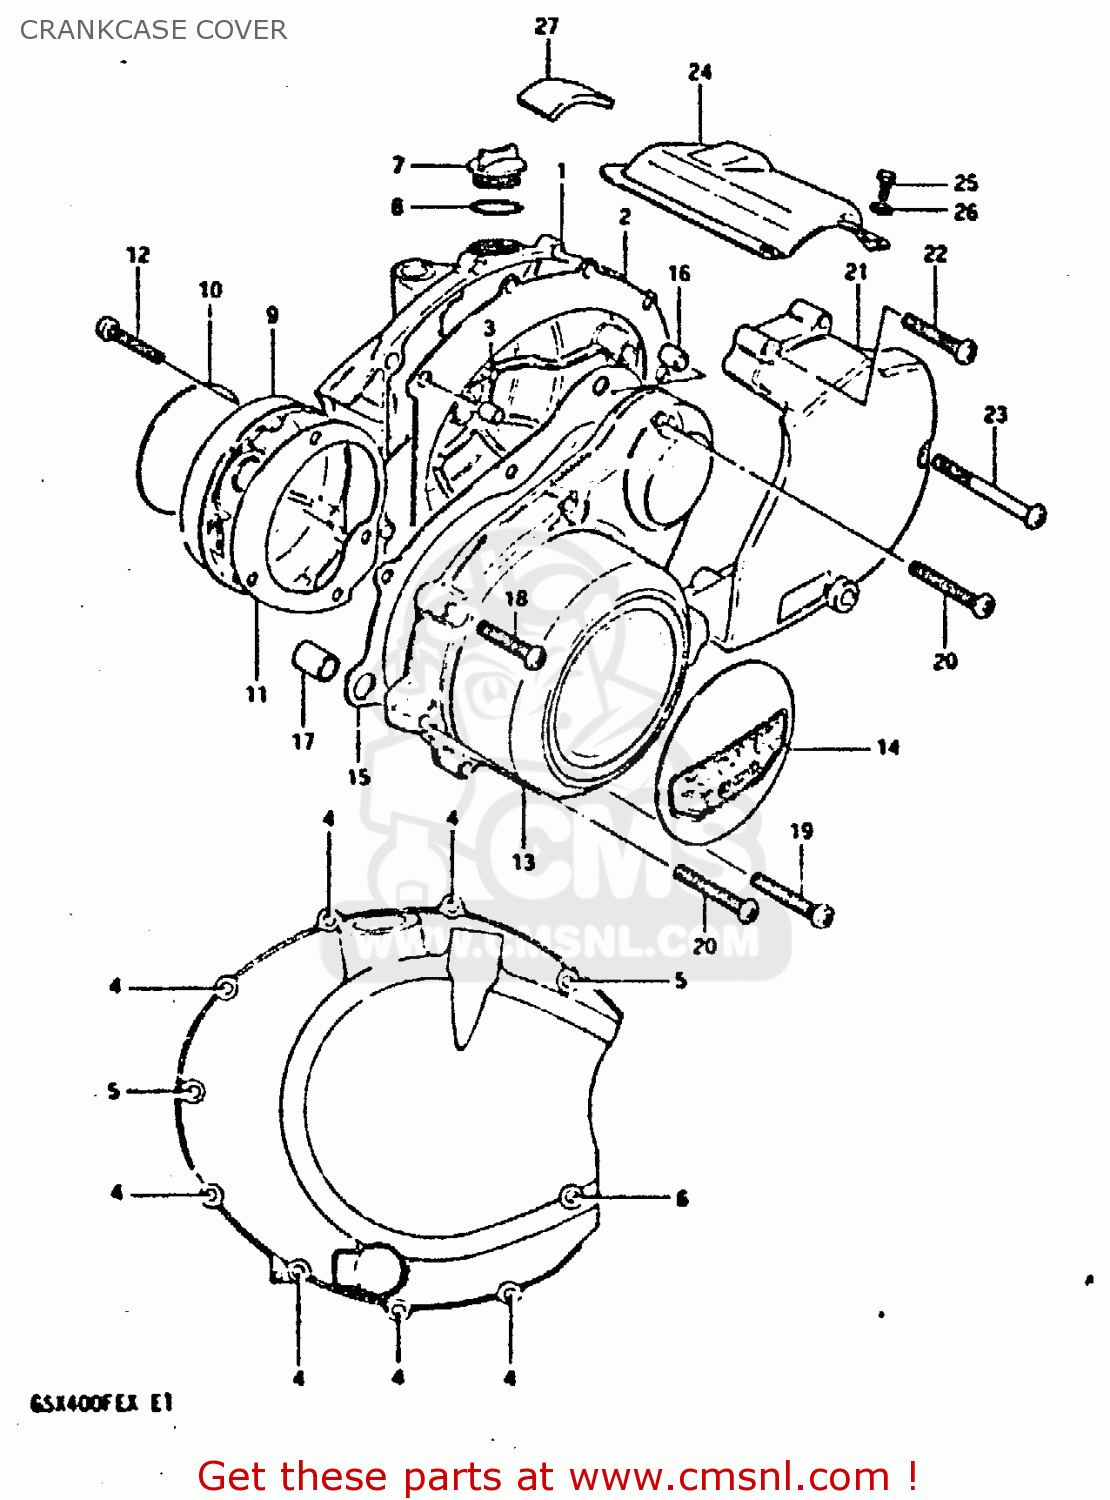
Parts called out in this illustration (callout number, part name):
1	COVER, CLUTCH
2	GASKET (MCA)
3	PIN
4	SCREW
5	SCREW 6X30
6	SCREW (6X45)
7	PLUG
8	O-RING
9	COVER, CONTACT BREAKER
10	EMBLEM,CONTACT
11	GASKET,CONTACT BREAKER COVER (MCA)
12	SCREW
13	COVER, GENERATOR
14	EMBLEM,MAGNETO COVER
15	GASKET (MCA)
16	PIN
17	PIN
18	SCREW 6X30
19	SCREW (6X35)
20	SCREW
21	COVER, ENGINE SPROCKET
22	SCREW (6X35)
23	SCREW 6X65
24	COVER
25	BOLT 5X16
26	WASHER
27	DAMPER,STARTER MOTOR CLUTCH
